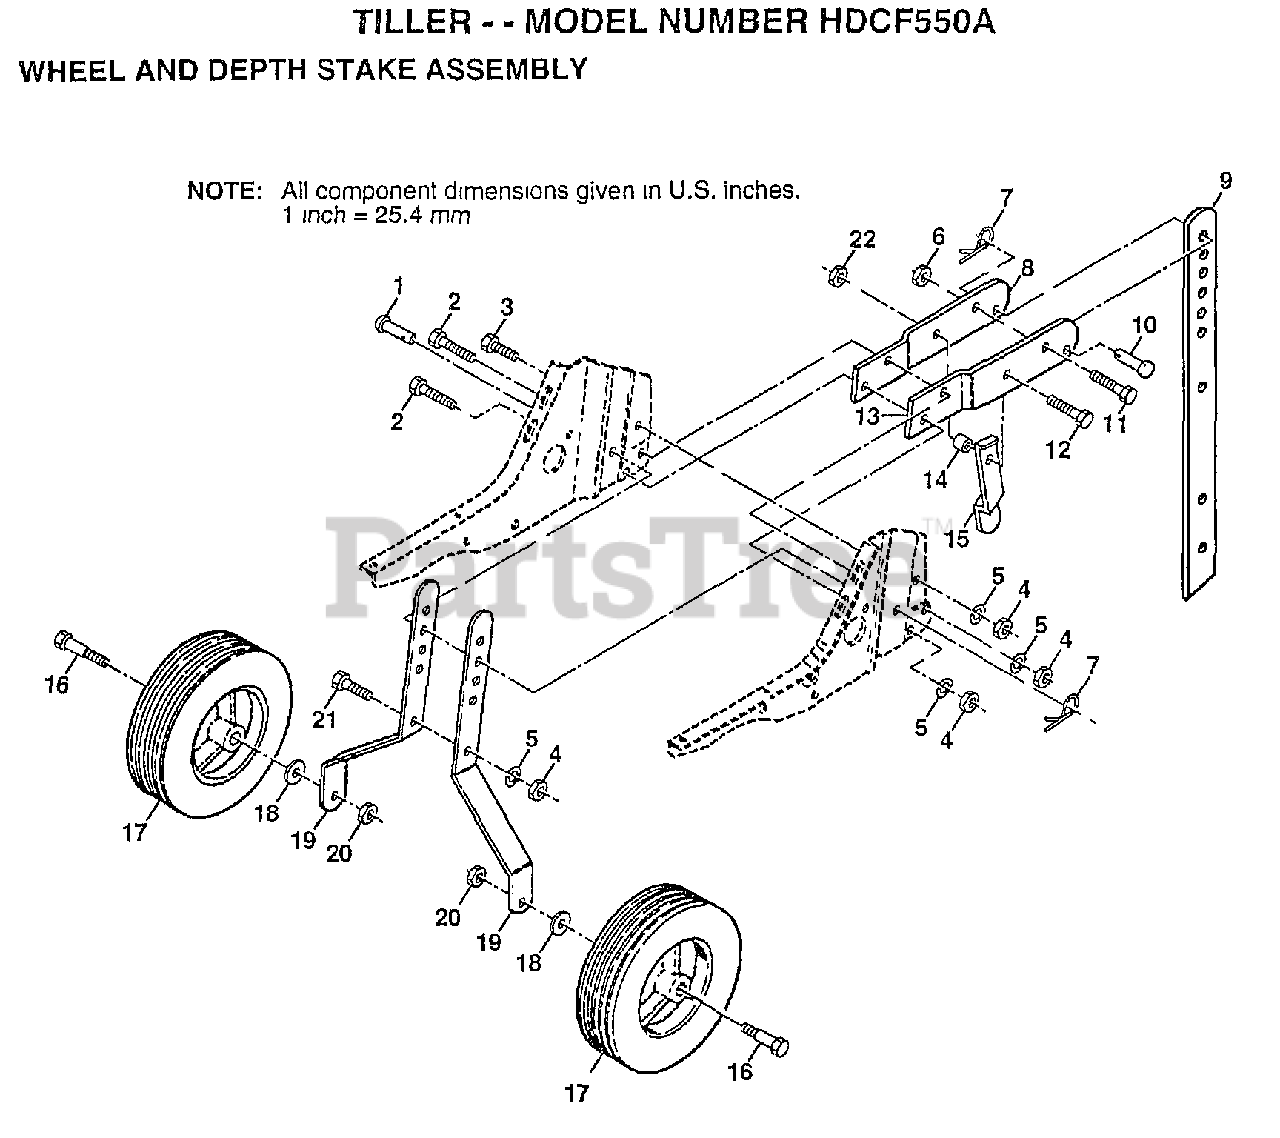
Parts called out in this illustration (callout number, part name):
1	DRILLED RIVET RT
3	BOLT
4	NUT.HEX.5/16-18
5	LOCKWASHER
6	NUT
7	SPRING.RETAINER
11	BOLT
12	BOLT.HEX.5/16-1.5
14	WASHER
15	STAKE SPRING TI
16	BOLT SHOULDER
18	WASHER
22	NUT
